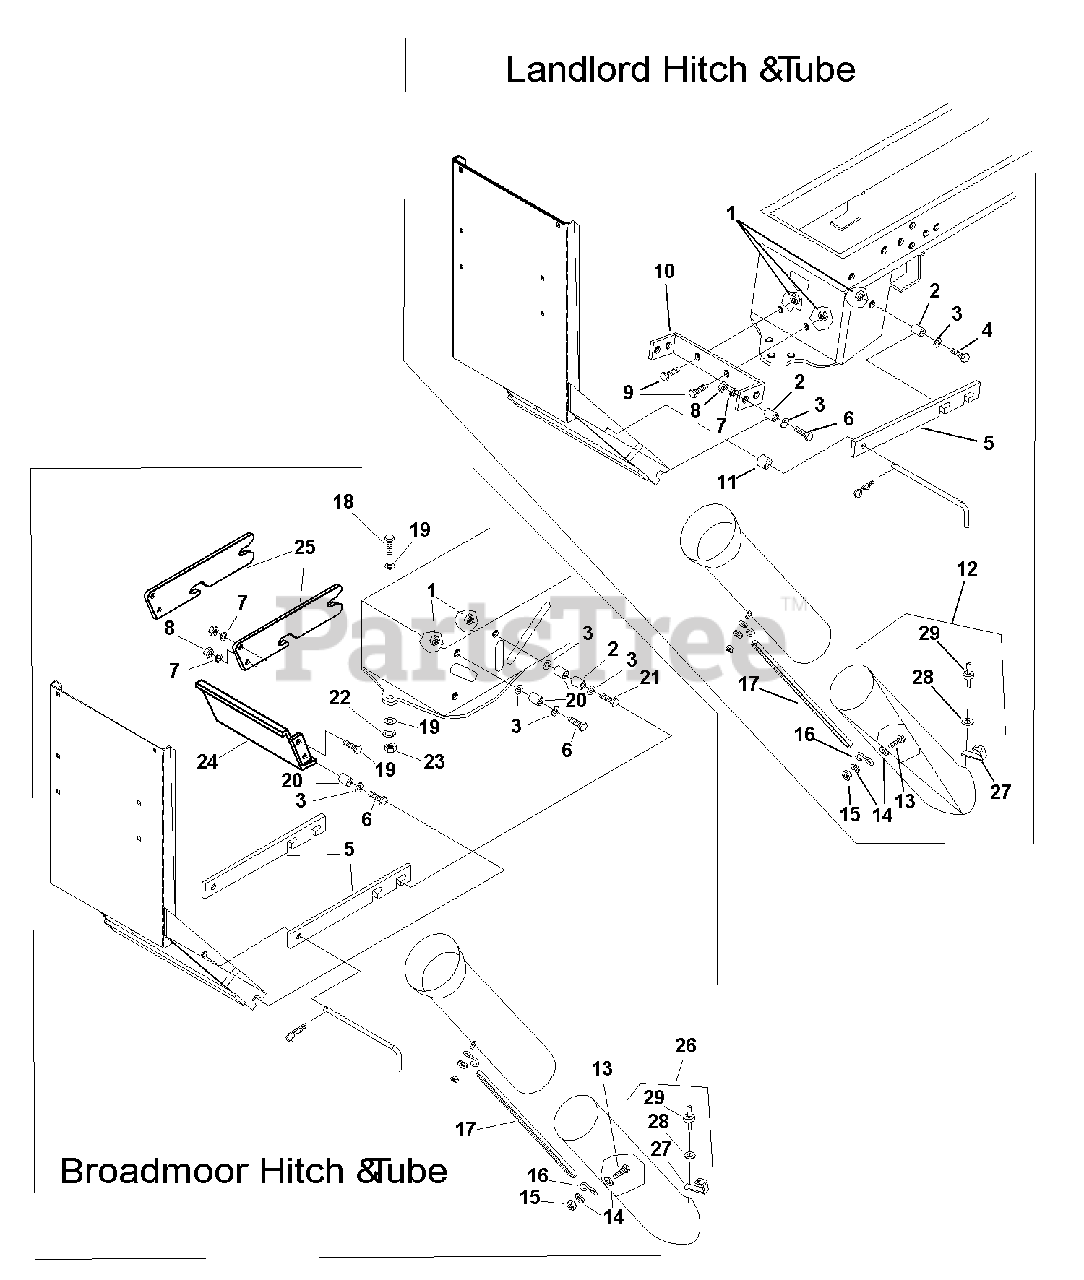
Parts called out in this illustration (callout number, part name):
1	NUT, Whizlock, 3/8-16
3	WASHER, 3/8
4	CAPSCREW, Hex Head, 3/8-16 X 1-3/8
5	SUPPORT ARM
6	CAPSCREW, Hex Head, 3/8-16 x 1-3/4
7	LOCKWASHER, 3/8
8	NUT, 3/8-16
9	CAPSCREW, Hex Head, 3/8-16 x 1
10	SUPPORT
12	TUBE & CLIP ASSEMBLY (Incl. Ref. Nos. 27, 28 & 29)
13	CAPSCREW, Hex Head, 1/4 x 1-1/4
14	WASHER
15	LOCKNUT, 1/4-20
18	CAPSCREW, Hex Head, 1/2-13 x 1-1/4
19	WASHER, 1/2
21	CAPSCREW, Hex Head, 3/8-16 x 2
22	LOCKWASHER, 1/2
23	NUT, Hex, 1/2-13
26	TUBE & CLIP ASSEMBLY (Incl. Ref. Nos. 27, 28 & 29)
27	CLIP
